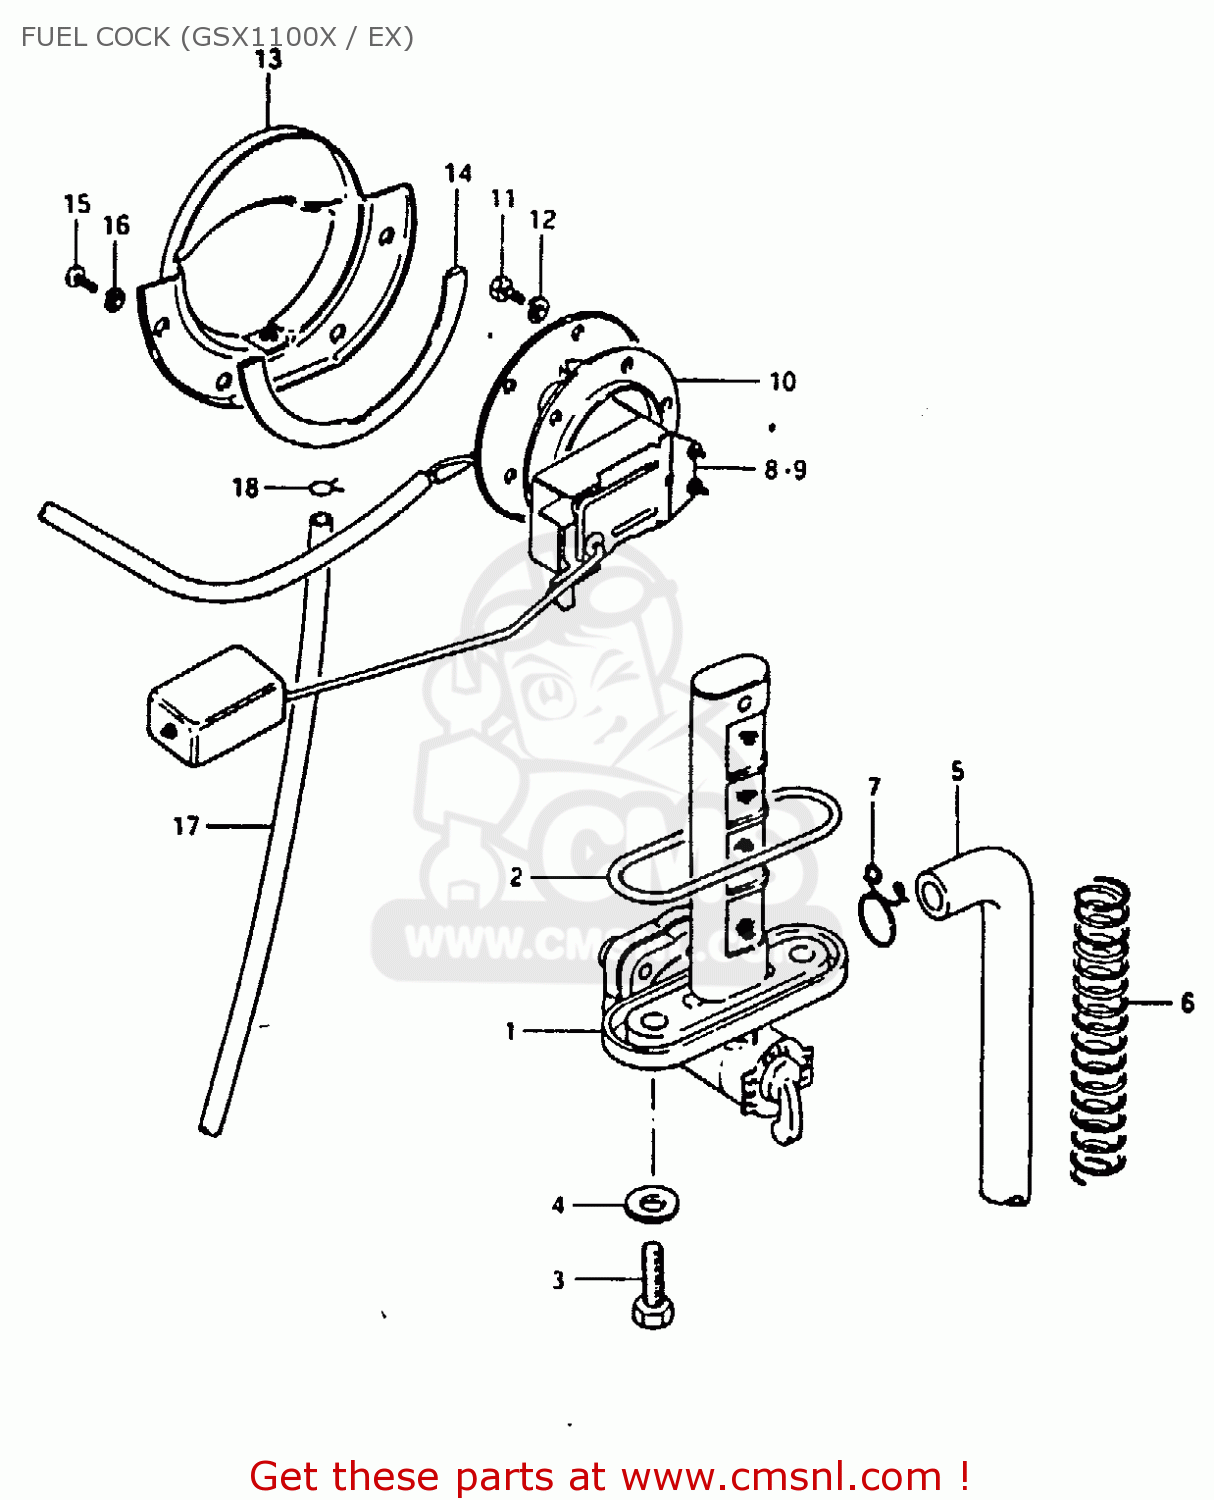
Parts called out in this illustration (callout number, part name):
1	COCK ASSEMBLY,FUEL
2	O RING
3	SCREW (6X25)
4	GASKET
5	HOSE
6	SPRING
7	CLIP
9	GAUGE, FUEL LEVEL (24L)
10	GASKET,FUEL LEVEL GAUGE (NAS)
11	BOLT
12	LOCK WASHER
13	PLATE,FUEL DRAIN
14	GASKET,FUEL DRAIN PLATE (NAS)
15	SCREW
16	LOCK WASHER
17	HOSE
18	CLIP
